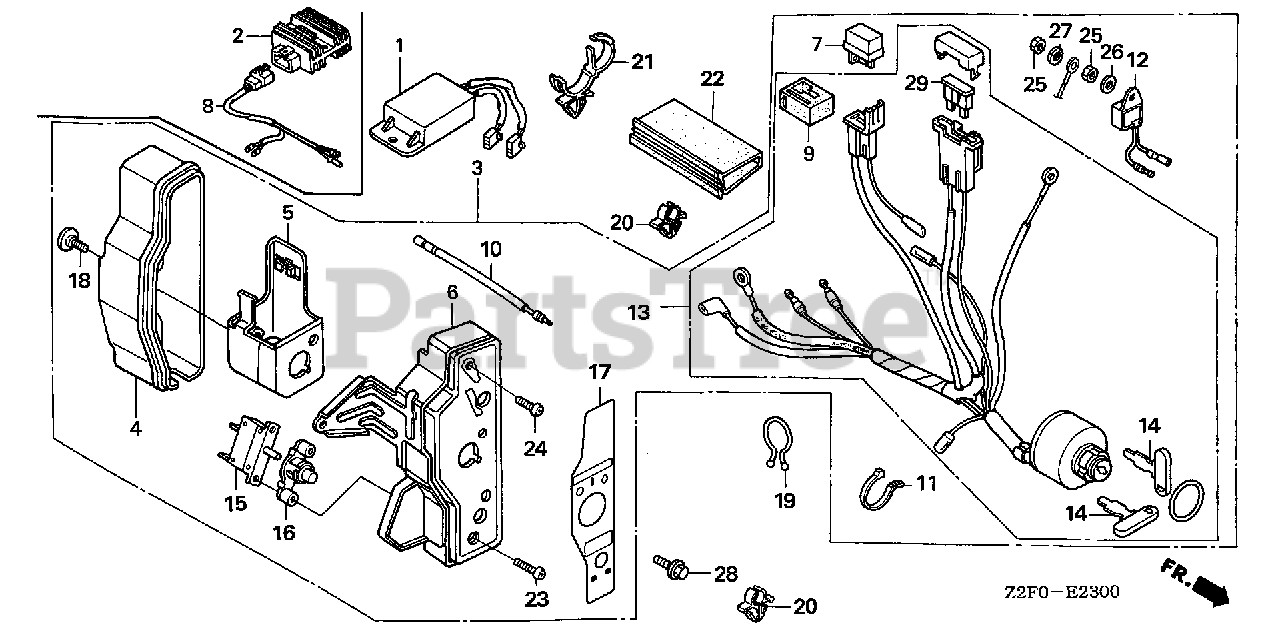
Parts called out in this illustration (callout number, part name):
1	RECTIFIER, REGULATOR
2	RECTIFIER ASSY., REGULATOR (10A)
3	BOX ASSY., CONTROL *R280* (INTL-ALERT) (POWER RED)
3	BOX ASSY., CONTROL *R280* (EXP-ALERT) (POWER RED)
4	CASE, CONTROL
5	BRACKET, CASE MOUNTING
6	PANEL, CONTROL *R280* (POWER RED)
7	RECTIFIER ASSY., SILICON (SHINDENGEN)
8	SUB-WIRE HARNESS ASSY.
9	SUSPENSION, CONNECTOR
10	SUB-WIRE HARNESS
11	BAND
12	ALERT UNIT, OIL
13	SWITCH ASSY., COMBINATION
14	KEY (HONDALOCK)
15	PROTECTOR, CIRCUIT (1.0A)
16	LENS ASSY., PROTECTOR
17	PANEL, CONTROL BOX (INTERNAL)
17	MARK, CONTROL BOX (EXP)
18	SCREW, SPECIAL (6X12)
19	CLIP, PURSE LOCK
20	CLIP, CORD
21	STRAP, WIRE HARNESS (25MM) (BLACK)
22	TUBE, FASTENER (30MM)
23	SCREW, PAN (3X12)
24	SCREW, PAN (4X12)
25	NUT, HEX. (4MM) (SOURCE: VINTAGE PARTS INC.)
26	WASHER, PLAIN (4MM)
27	WASHER, SPRING (4MM)
28	BOLT, FLANGE (6X10)
29	FUSE, BLADE (5A)
